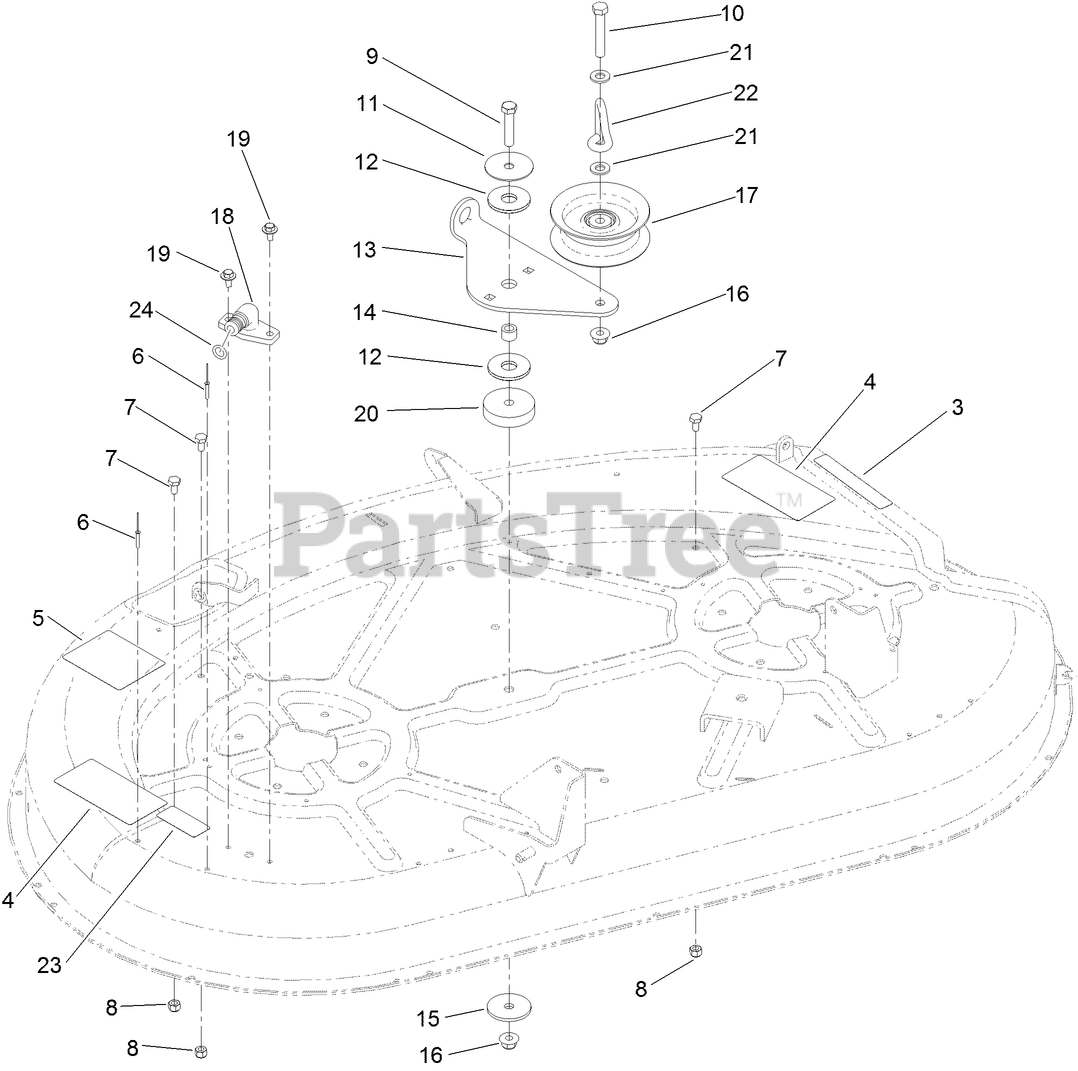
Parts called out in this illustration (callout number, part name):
3	DECAL-DANGER
4	DECAL-DANGER, DECK
5	DECAL-ROUTING, BELT
6	RIVET-BLIND
7	SCREW-HH
8	NUT-LOCK, NI
9	SCREW-HH
10	SCREW-HH
11	WASHER
12	WASHER-FRICTION, COMPOSITE
13	ARM-IDLER
14	SPACER
15	WASHER-REBOUND
16	NUT-HF, NI
17	PULLEY-IDLER, FLAT
18	FITTING-WASHOUT
19	SCREW-HHFTF
20	WASHER-CLUTCH
21	WASHER-FLAT
22	GUIDE-IDLER, BELT
23	DECAL-SERVICE
24	O-RING
